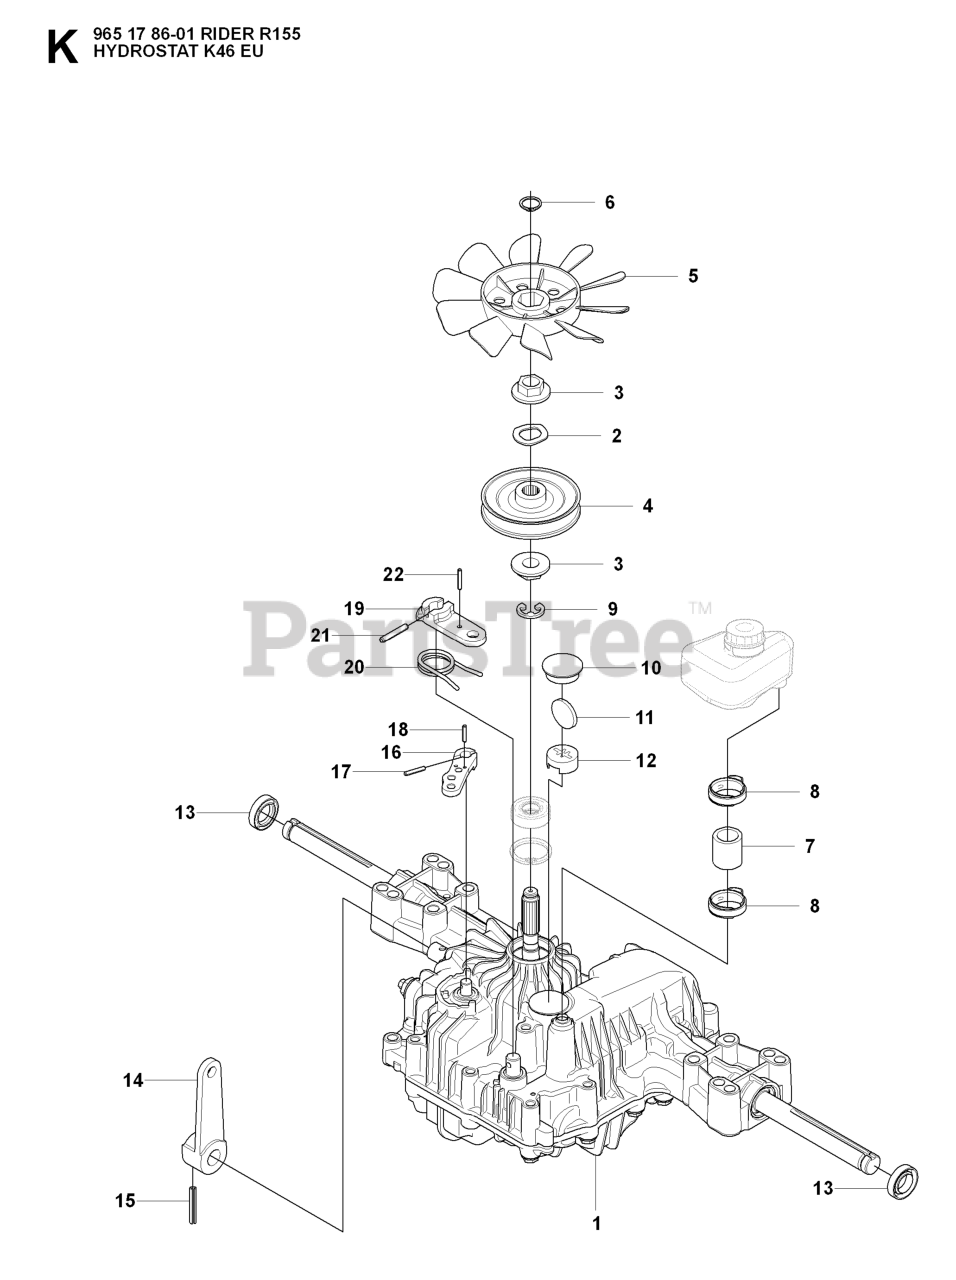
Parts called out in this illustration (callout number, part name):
1	HYDROSTAT 7A646024070
4	PULLEY - 3 1/2"
5	FAN.BLACK.1A646083070
6	RETAINING RING **
7	PIPE
8	CLAMP
9	Retaining Ring
13	RP SEAL.19, 19216334280
20	RETURN SPRING
